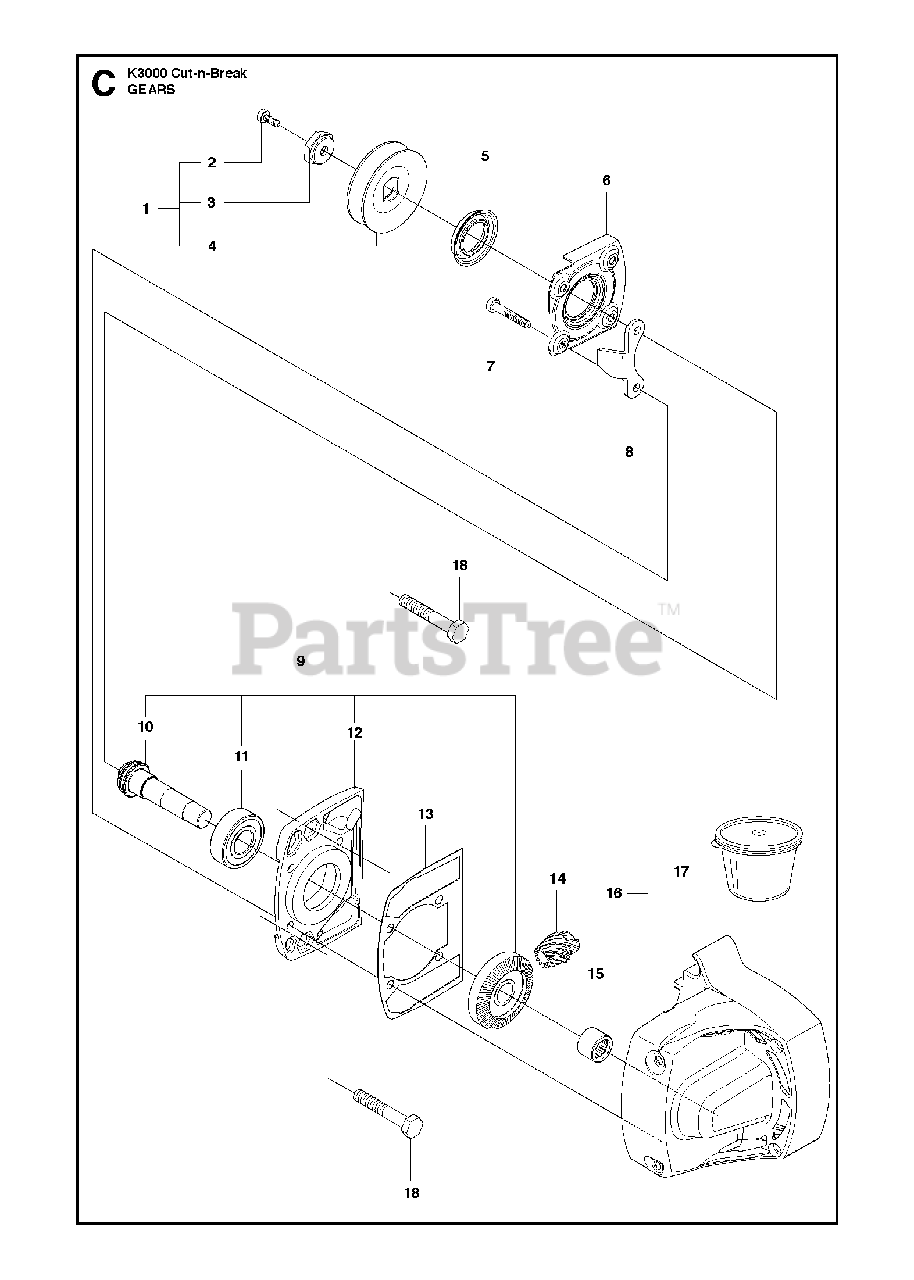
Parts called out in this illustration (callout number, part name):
1	DRIVING PULLEY ASSYIncl. 2 - 4
2	SCREW ITXSCM
7	SCREW ITXSCM
9	GEAR SETIncl. 10 - 12
11	BALL BEARING
15	NEEDLE BEARING
17	GREASE
